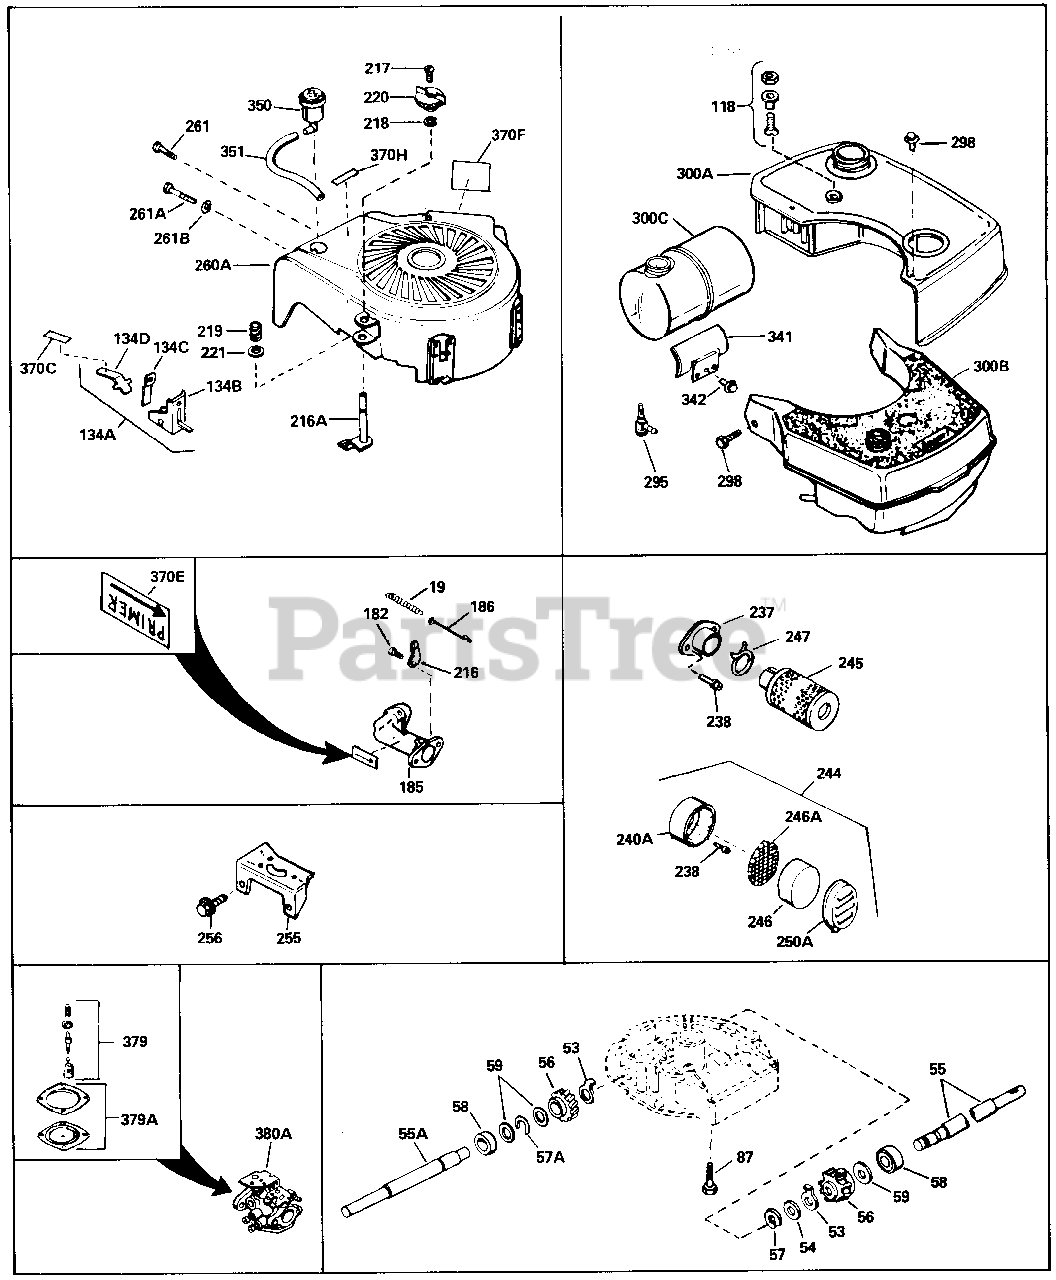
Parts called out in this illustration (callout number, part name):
19	Spring, Governor
53	Washer, Tang
54	Washer, Thrust
55	Shaft, P.T.O.
56	Right Hand Worm Gear
57	Ring, Retaining
58	Oil Seal
59	Washer, Flat
87	Screw, 1/4-20 x 2-1/4"
182	Screw, 1/4-28 x 7/8"
185	Pipe, Intake
186	Link, Governor spring
245	Air Filter
247	Clamp, Corbin
260A	Housing, Blower NOTE: Replacement har dware may differ when servicing start er assy. or blower housing. Refer to Service Bulletin 508.
298	Screw, 10-32 x 35/64"
300B	Fuel Tank Ass'y. (Incl. 301)
350	Primer Assy.
351	Line, Primer
379	Inlet Needle, Seat & Clip Assy.
